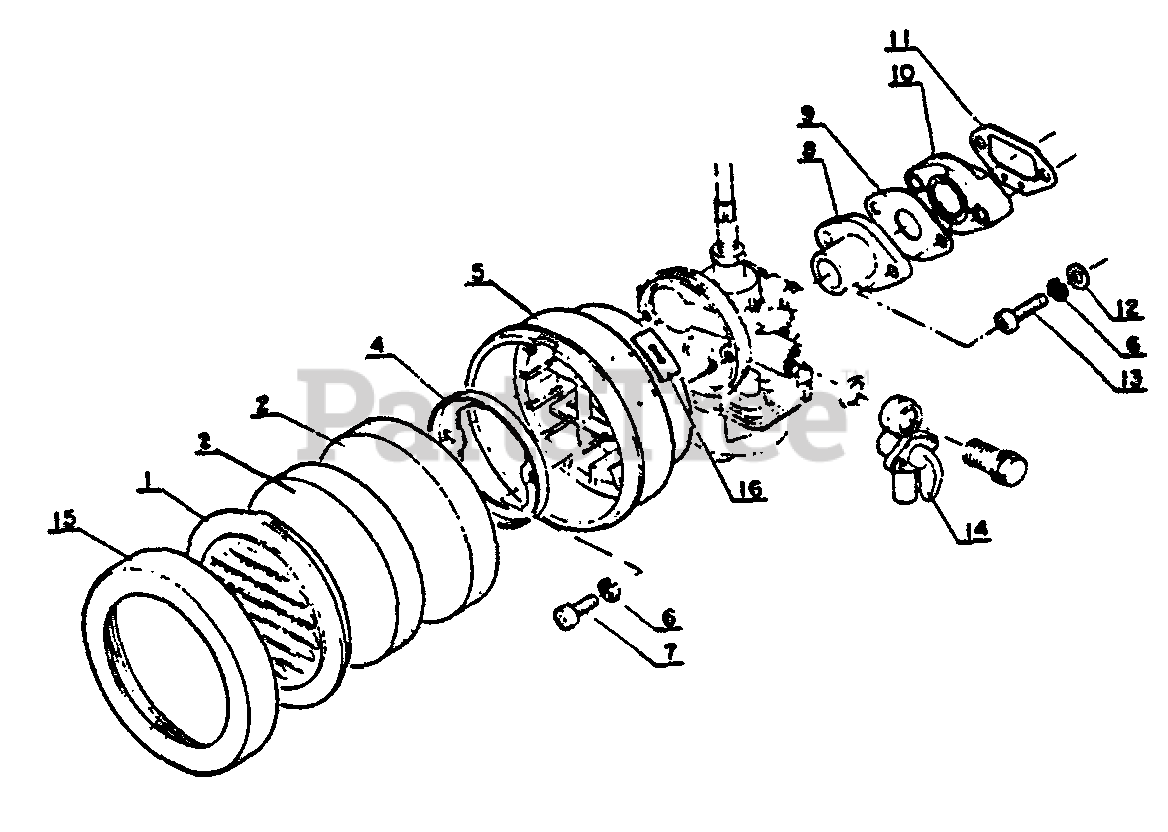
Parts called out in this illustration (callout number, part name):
1	COVER, AIR FILTER
2	FILTER, AIR
4	BRACKET, AIR FILTER
5	CASE, AIR FILTER
6	WASHER, SPRING 4 MM
7	SCREW 4×10
8	ADAPTER, INTAKE
9	GASKET, INTAKE
10	INSULATOR, INTAKE
11	GASKET, INTAKE
12	WASHER 4 MM
13	SCREW 4×25
14	FUEL VALVE ASSY
15	COVER, AIR FILTER
16	LABEL - CHOKE
